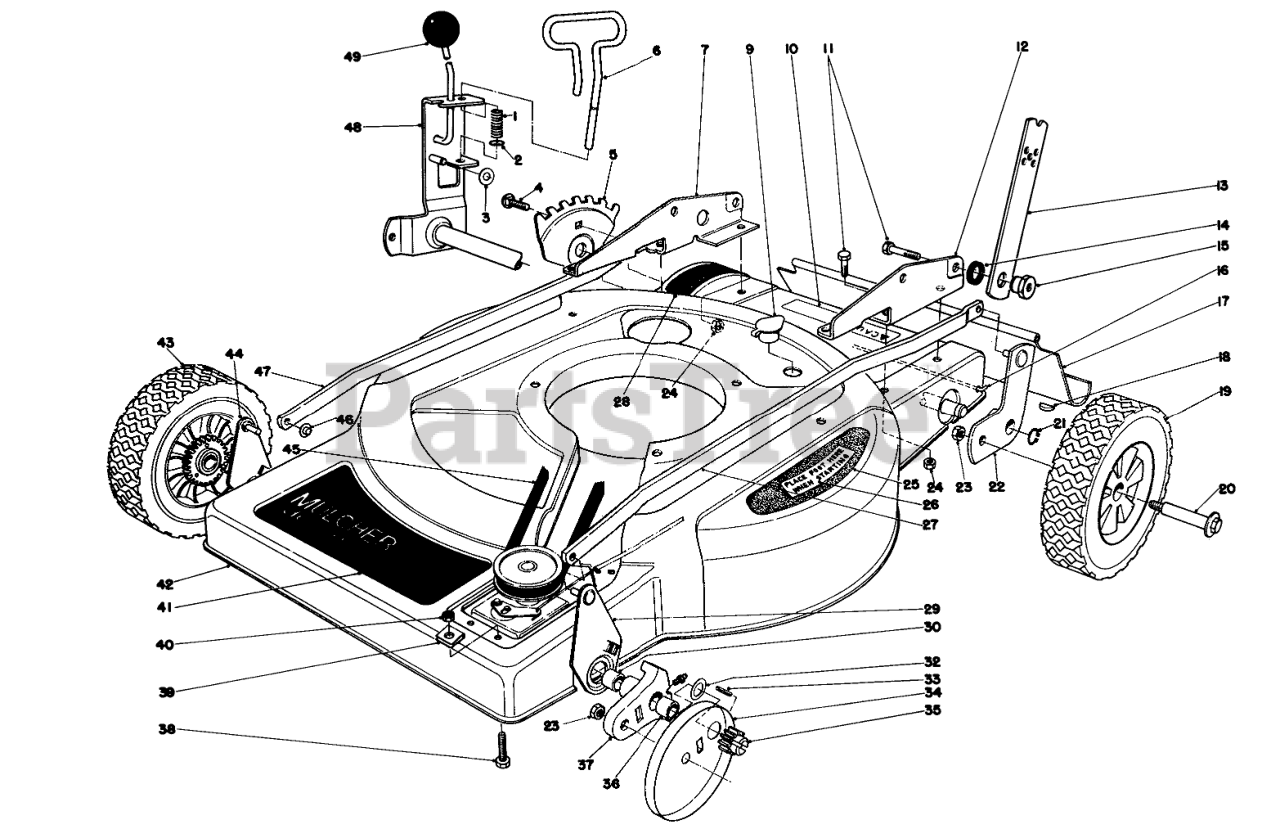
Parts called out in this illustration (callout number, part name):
1	SPRING-COMPRESSION
2	E-RING
3	WASHER-FLAT
4	Carriage Bolt
5	HOC ADJUSTMENT PLT
6	STOP ROD
7	Bracket Handle R.H.
9	WASHOUT PLUG
10	Caution Decal
11	SCREW-HH
12	Bracket-Handle R.H.
13	HANDLE LATCH
14	SPACER
15	HANDLE PIVOT NUT
16	SHIELD ROD
17	SHIELD - TRAILING
18	KEY-WOODRUFF
19	WHEEL TIRE ASM 8 IN
20	BOLT-WHEEL
21	RING-RETAINING
22	Pivot Arm
23	Nut
24	NUT-LOCK, CONE
25	PAD STEP
26	Decal Step Pad
27	Spanner Link L.H.
28	Decal Height of Cut
29	Link Pivot Arm L.H.
30	BUSHING
32	WASHER-THRUST
33	Pin
34	WHEEL COVER
35	Pinion
36	BUSHING
37	Pivot Arm (Incl. Ref. #30 & 36)
38	SCREW
39	SPEED NUT
40	NUT-LOCK
41	Decal-Front Deck
42	Housing
43	Wheel & Tire Assembly
44	Link Pivot Arm R.H.
45	V BELT
46	NUT-SPEED
47	Spanner Link R.H.
48	Pivot Arm Bracket
